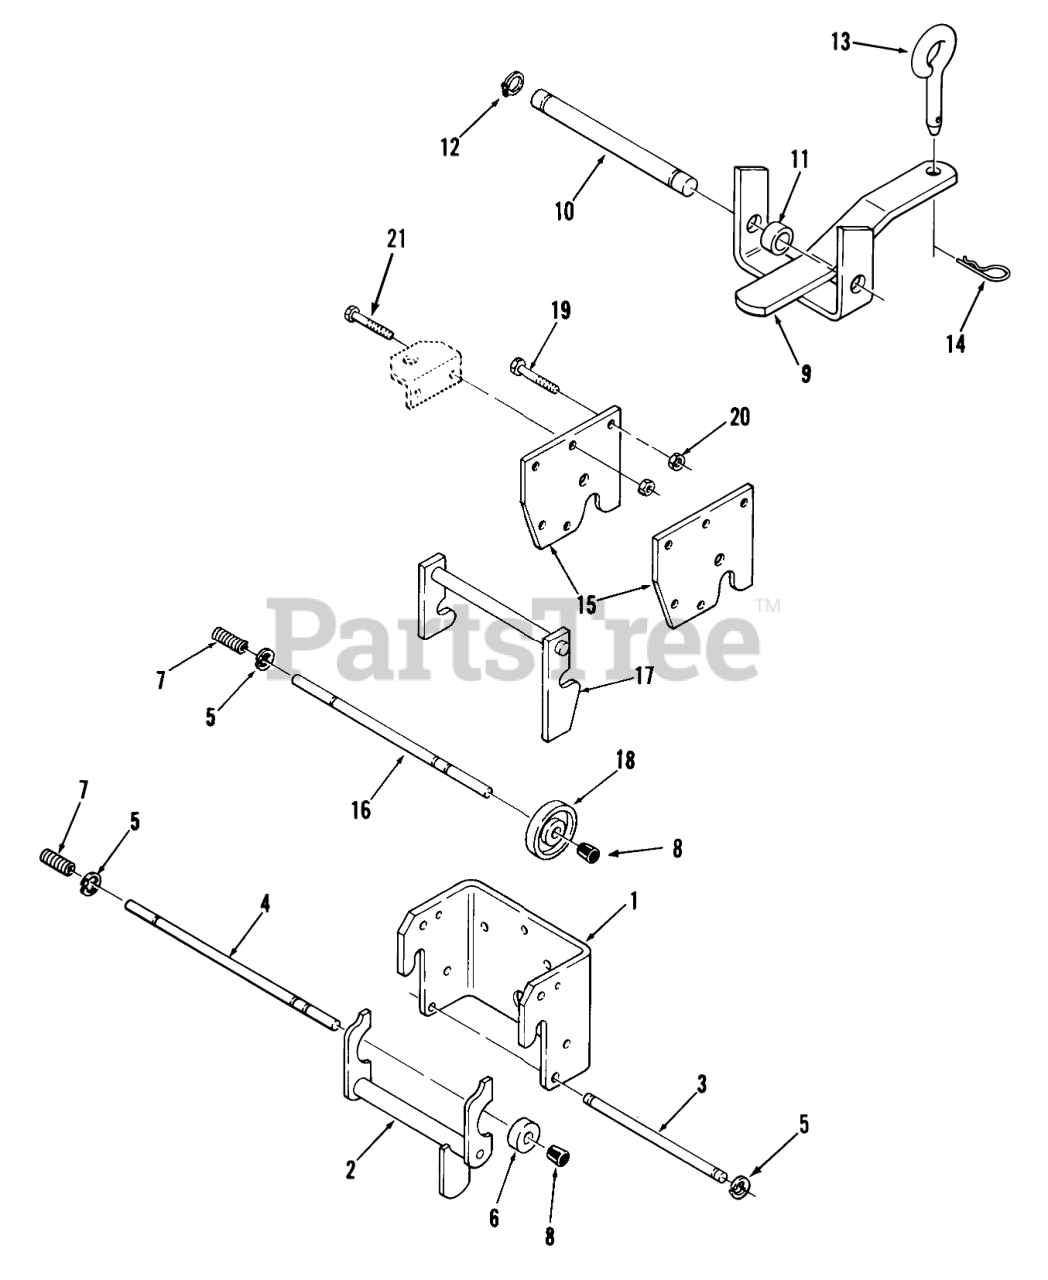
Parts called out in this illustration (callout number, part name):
1	Front Hitch
2	Assy-Latch
3	ROD-LATCH PIVOT
4	ROD-LOCK
5	RING-RETAINING
7	SPRING
8	CAP-ROD, PLUNGER
9	Hitch
10	PIN-STATIONARY HITCH
11	Spacer
12	E-RING
13	PIN-TOOL
14	Hairpin Cotter
15	Hitch Plate
17	ASSY MID HITCH LA R
19	BOLT
20	NUT
21	Bolt
